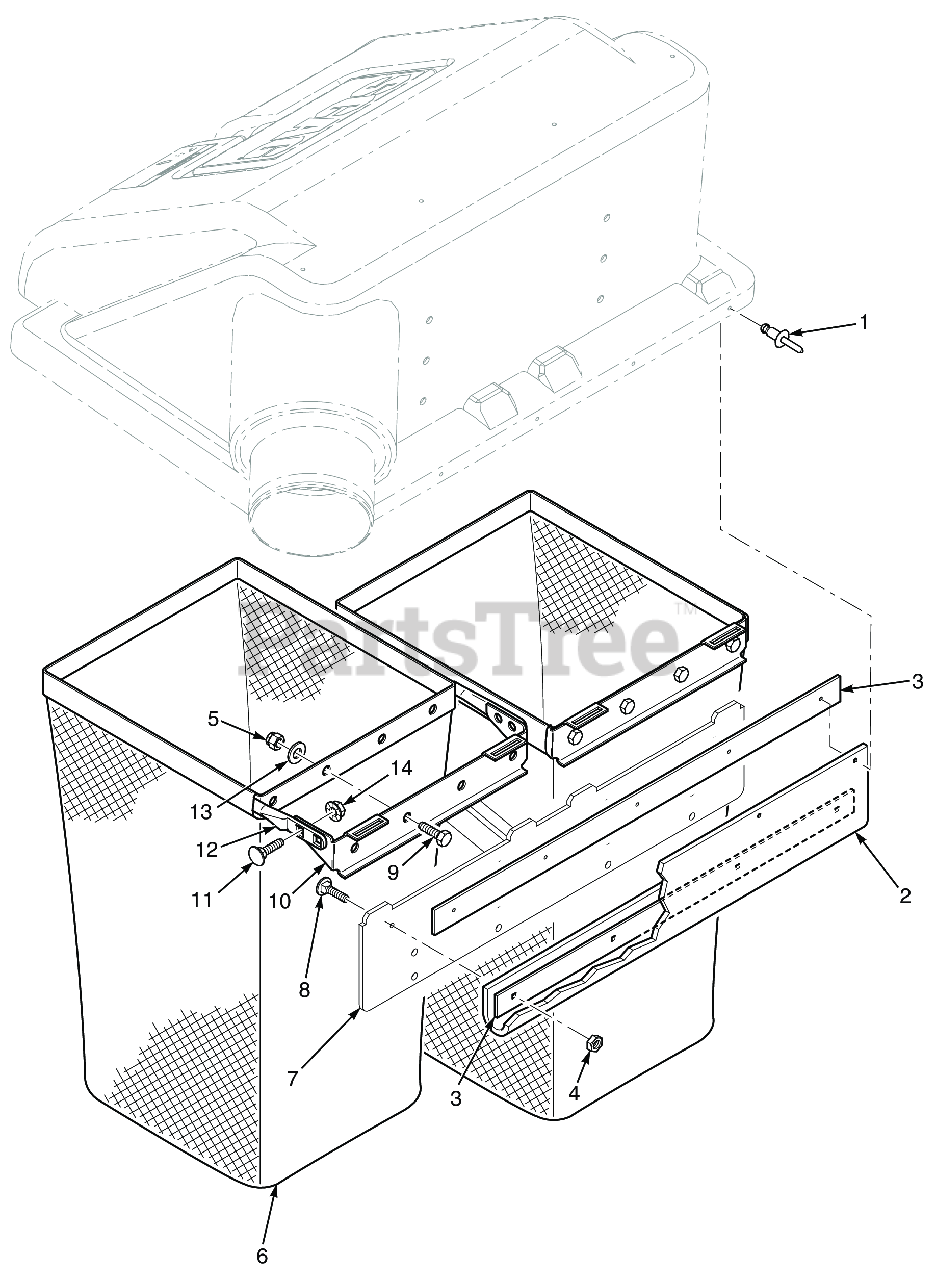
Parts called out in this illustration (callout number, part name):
1	Pop Rivet, 3/16 x .652"
2	Diode (part of wire harness)
3	Retainer, Seal
4	Bolt, Hex Hd. 1/2-13 x 9-1/2"
5	HEX NUT, ELASTIC STOP LOCK, 5/16-18
6	Bag Assembly
7	Frame Weldment, Bag Support
8	BOLT, HEX HEAD, 1/4-20 X 3/4 GR.5
9	BOLT, SERRATED FLANGE HEX HEAD 5/16-18 X 3/4"
10	Mount, Bag Frame Tube
11	Bolt, 5/16-18 x .75 RHSN Carriage
12	Tube, Bag Support
13	Flatwasher, 5/16-.375 x .875 x .083 (35BV & 37BV-EFI)
14	Nut, Serrated Flange 5/16-18 (Right Front Engine Mounting, Briggs and Kohler Only)
